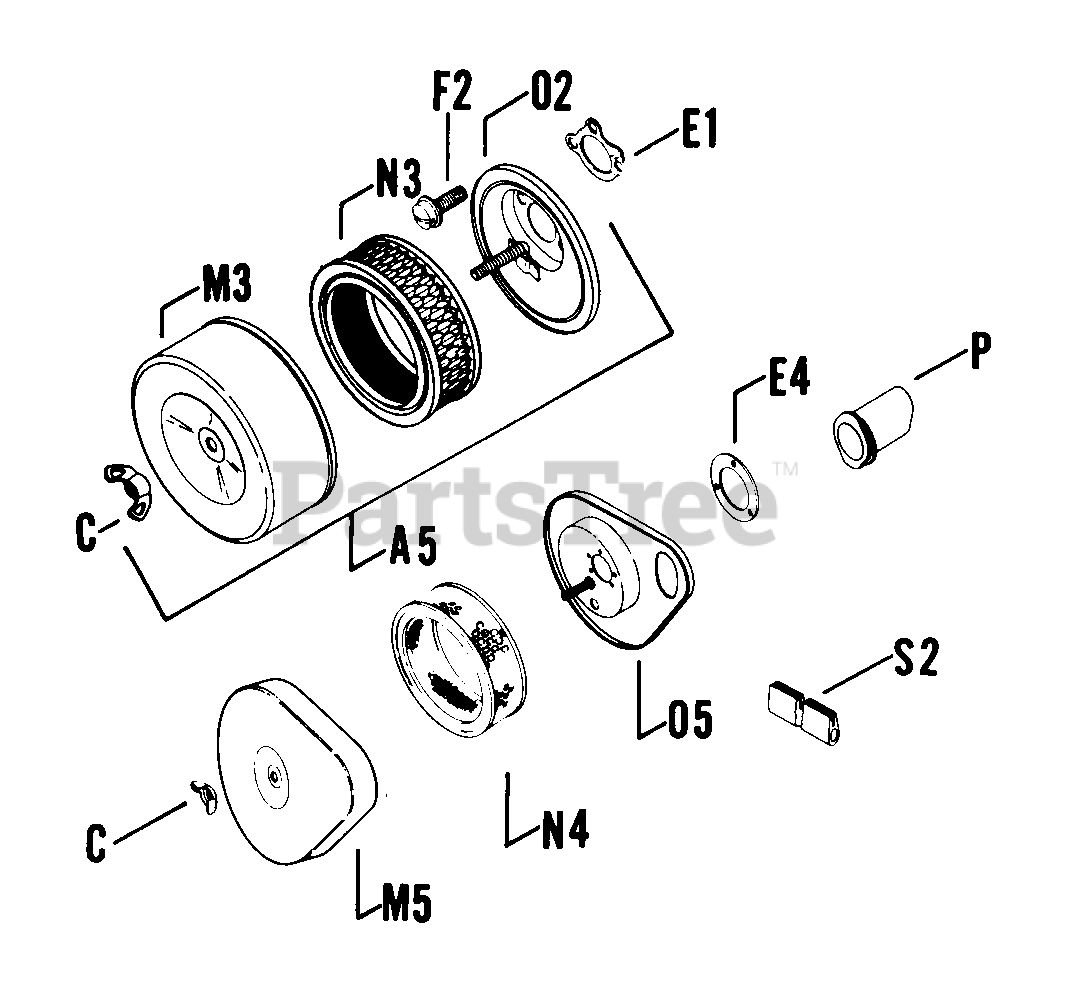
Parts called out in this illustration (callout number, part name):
A5	CLEANER - DISCONTINUED
C	NUT, WING 1/4-20 USE 25 100 15-S
M3	COVER, AIR CLEANER - DISCONTINUED
N3	AIR FILTER/PRE-CLEANER KIT USE 25 883 03-S1
O2	BASE, AIR CLEANER - DISCONTINUED
